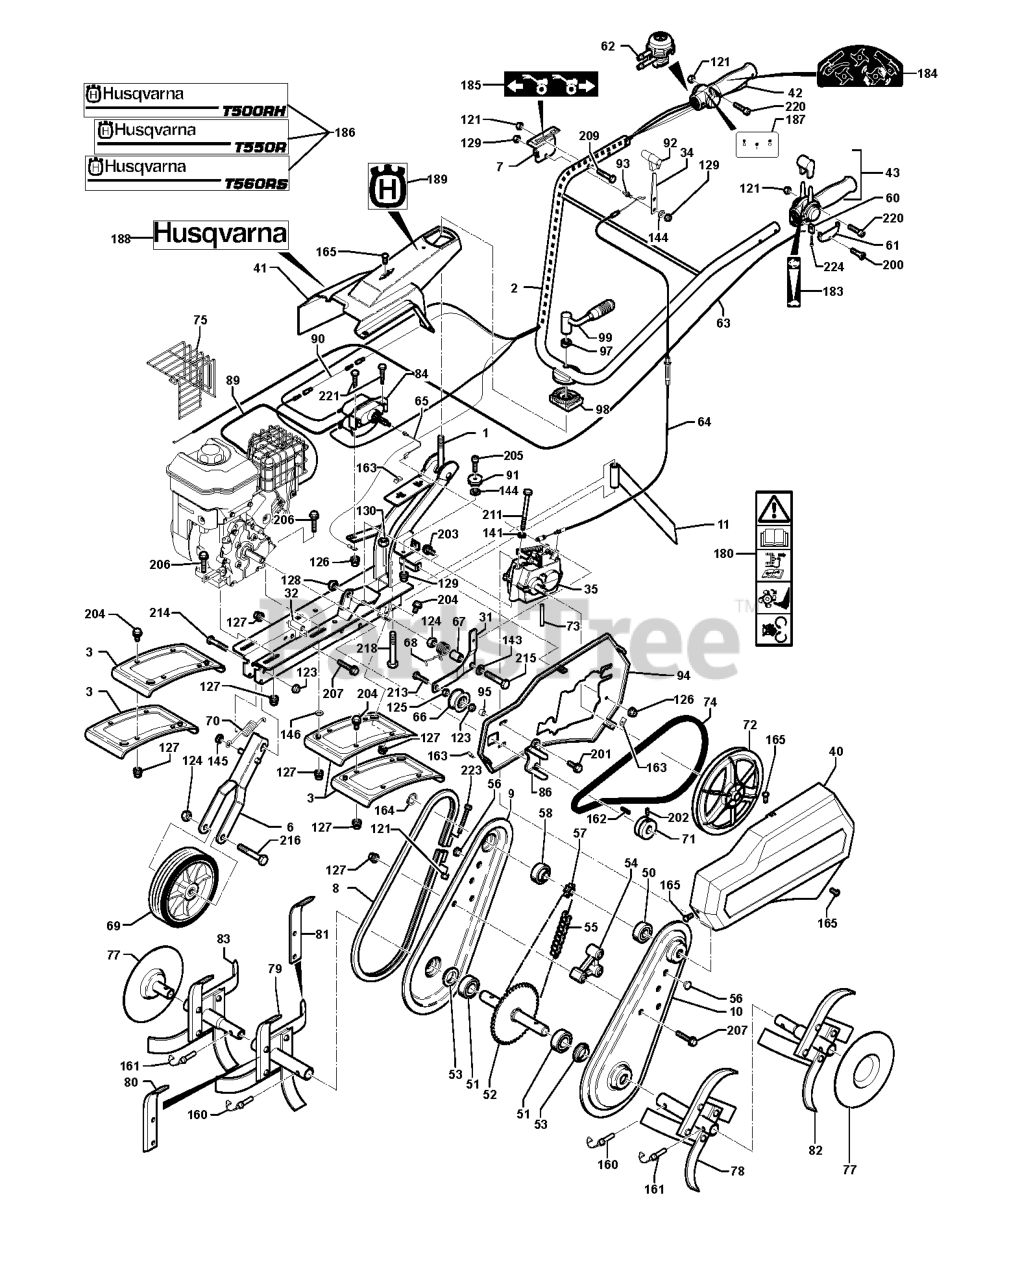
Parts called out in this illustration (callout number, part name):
31	ARM
55	DRIVE CHAIN
69	WHEEL
121	Blocking nut M 6 Z
164	RETAINING RING
